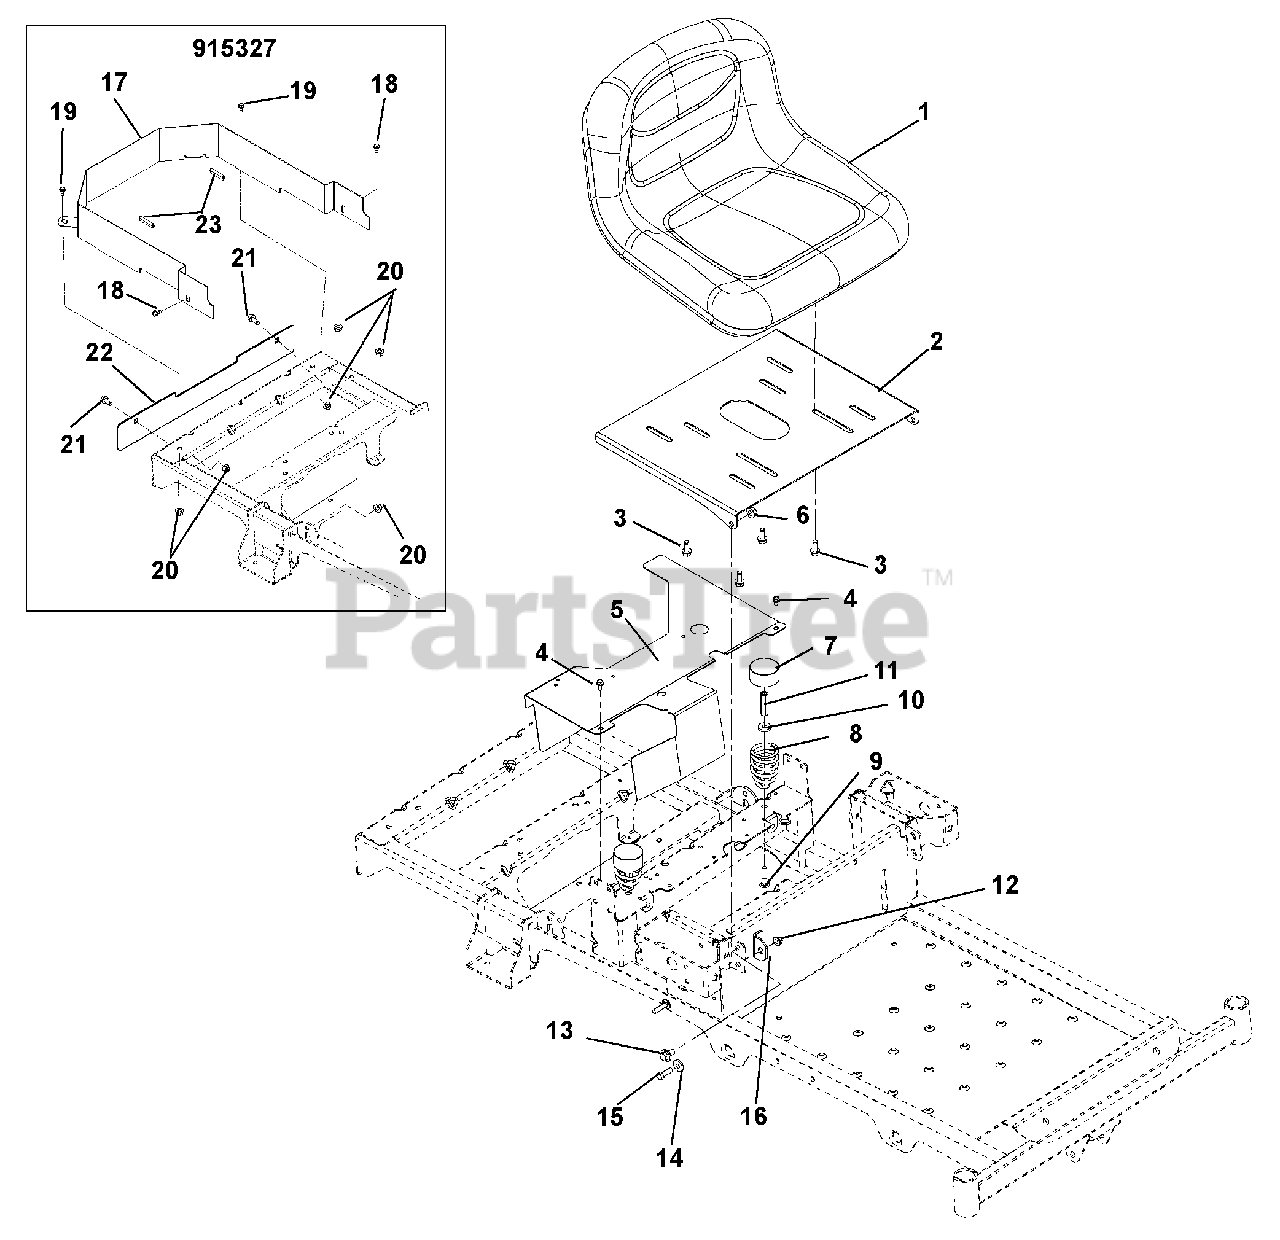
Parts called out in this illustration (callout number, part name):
1	Seat, 13 in Grey
2	Seat Plate
3	Bolt, Hex 5/16-18 x 3/4
4	Screw, Tapping .25-20 x .50 Hex Washer Head Thread
5	Cover, Zoom CE Fan
6	Nut, .38-16 Locking Top Flange
8	Spring, Seat
9	Bolt, Round Head Square Neck .31-18 x 1.50
10	Washer, Flat Steel .328 x .87 x .179
11	Nut, Coupling 5/16-18 x 1.75
12	Nut, 5/16-18 Flange Nyloc
13	Bolt, Shoulder .375-16 x .135
14	Bushing, Flange .325 x .499 x .26 x .88
15	Bolt, Hex .31-18 x 1.00
16	Bracket, Seat Stop
17	Shield, ZT CE Reach-In
18	Bolt, Hex .38-16 x .75 Grade 5 YWCZ
19	Bolt, Hex .38-16 x 1.00 Grade 5 YWZC
20	Nut, Locking Center .38-16
21	Bolt, Round Head Square Neck .38-16 x .75 Grade 5 YWZC
22	Flange, Muffler Zoom CE
23	Edging, Molded
